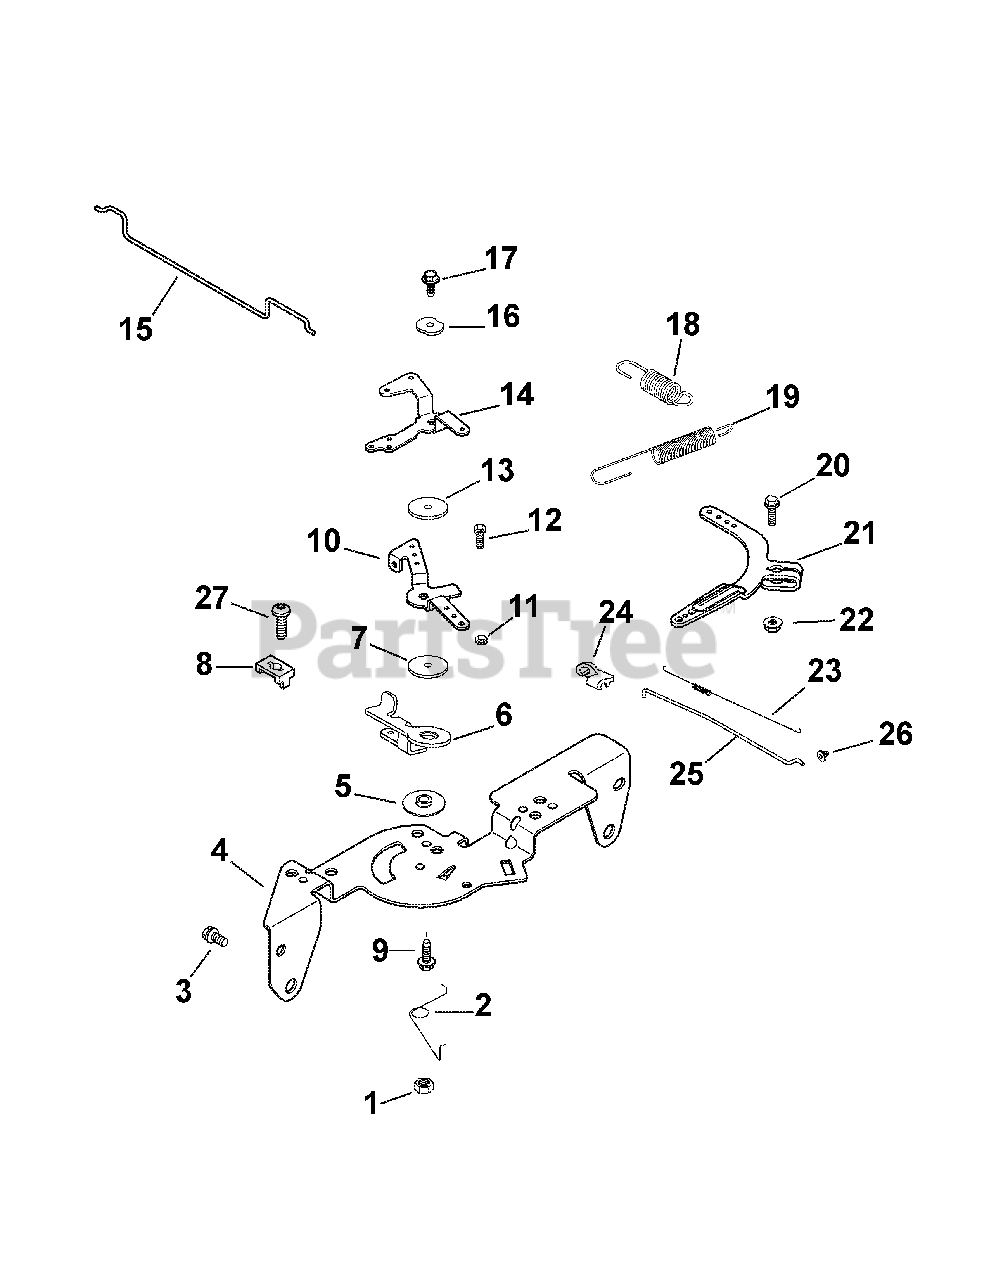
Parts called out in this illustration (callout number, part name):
1	Nut, hex. lock M5x0.8
2	Spring, choke return
3	Screw, hex flange M6x1.0x16
4	Bracket, control
5	Spacer, control assembly
6	Lever, throttle actuator
7	Washer, flat, 5mm
8	Clamp, cable
9	Screw, hex. flange M5x0.8x16
10	Lever, throttle control
12	Screw, cap M4x0.7x30
13	Washer, flat, 5.5 mm
14	Lever, choke
15	Linkage, choke
16	Washer, spring 1/4"
17	Screw, hex. flange M5x0.8x20
18	Spring, governor
19	Spring, governor
20	Bolt, rd hd sq neck, M6x1.0x25
21	Lever, governor
22	Nut, flange M6x1.0
23	Spring, linkage
24	Bushing, linkage retaining
25	Linkage, throttle
26	Bushing, throttle linkage
27	Screw, lbd thd frm, M5 x 0.8 x 16
